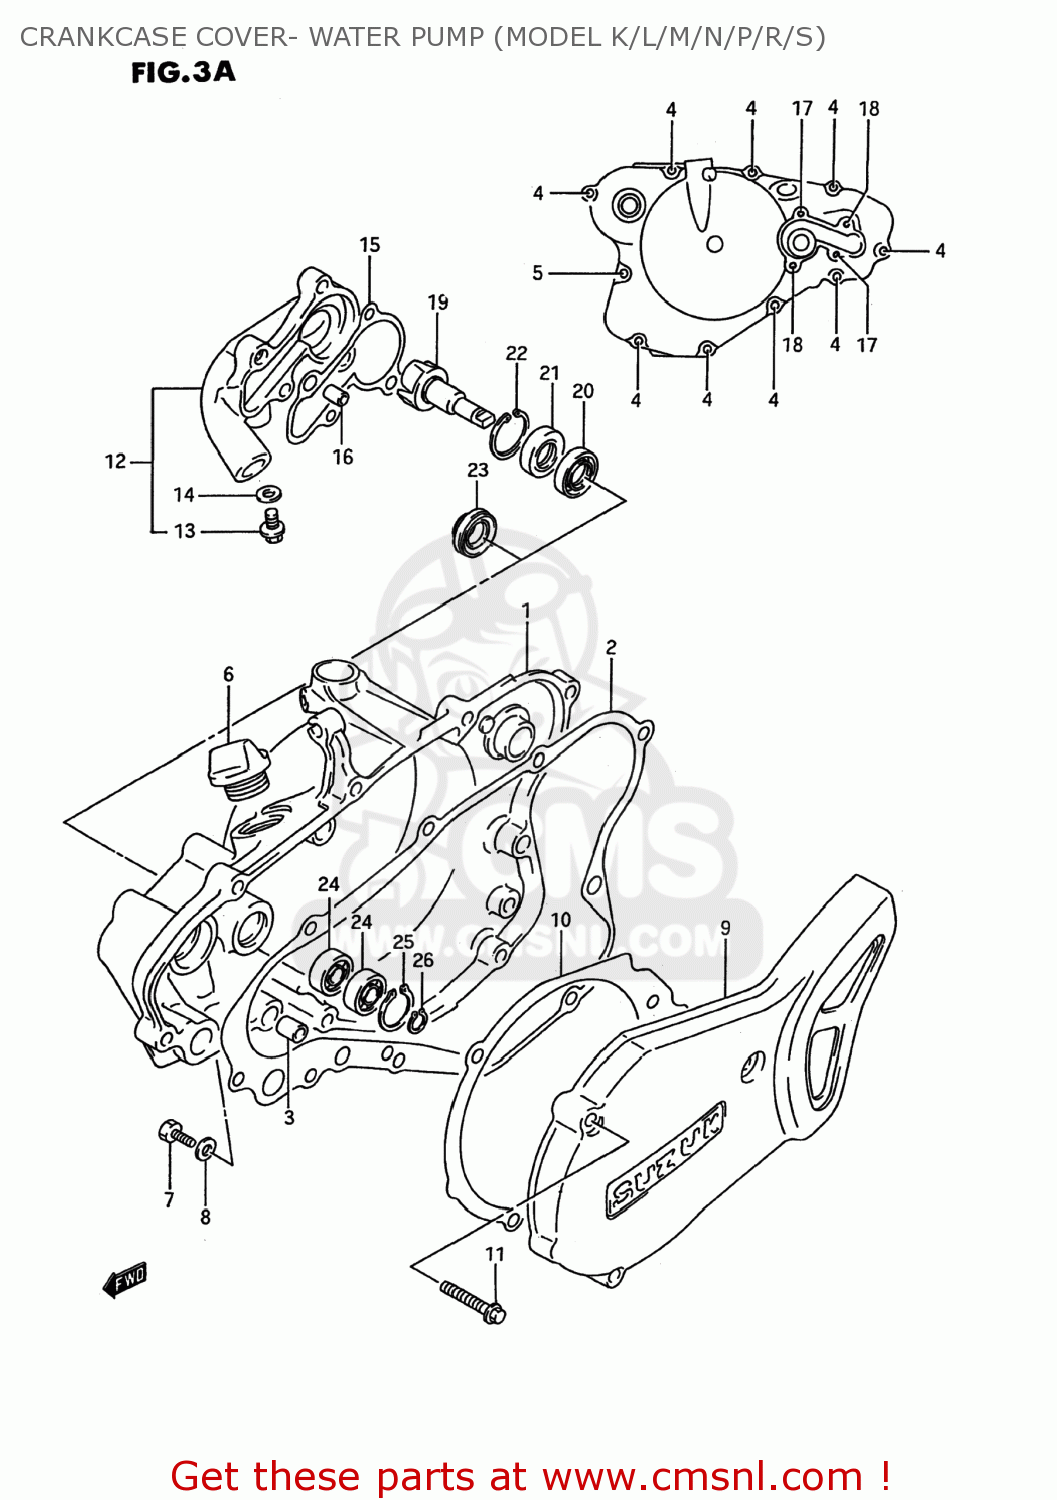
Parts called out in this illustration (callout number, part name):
1	COVER,CLUTCH
2	GASKET,CLUTCH COVER (NAS)
3	PIN
4	BOLT
5	BOLT
6	PLUG SET
7	SCREW(6X10)
8	GASKET(6.2X11X1).2 (NAS)
9	COVER,MAGNETO
10	GASKET,MAGNETO COVER (NAS)
11	BOLT
12	CASE,WATER PUMP
13	BOLT
14	WASHER
15	GASKET,WATER PUMP CASE (NAS)
16	PIN
17	BOLT
18	BOLT
19	IMPELLER,WATER PUMP
20	SEAL,OIL(12X24X3.6)
21	SEAL,OIL(12X24X6.4)
22	CIRCLIP
23	SEAL,WATER PUMP OIL
24	BEARING
25	CIRCLIP
26	CIRCLIP
